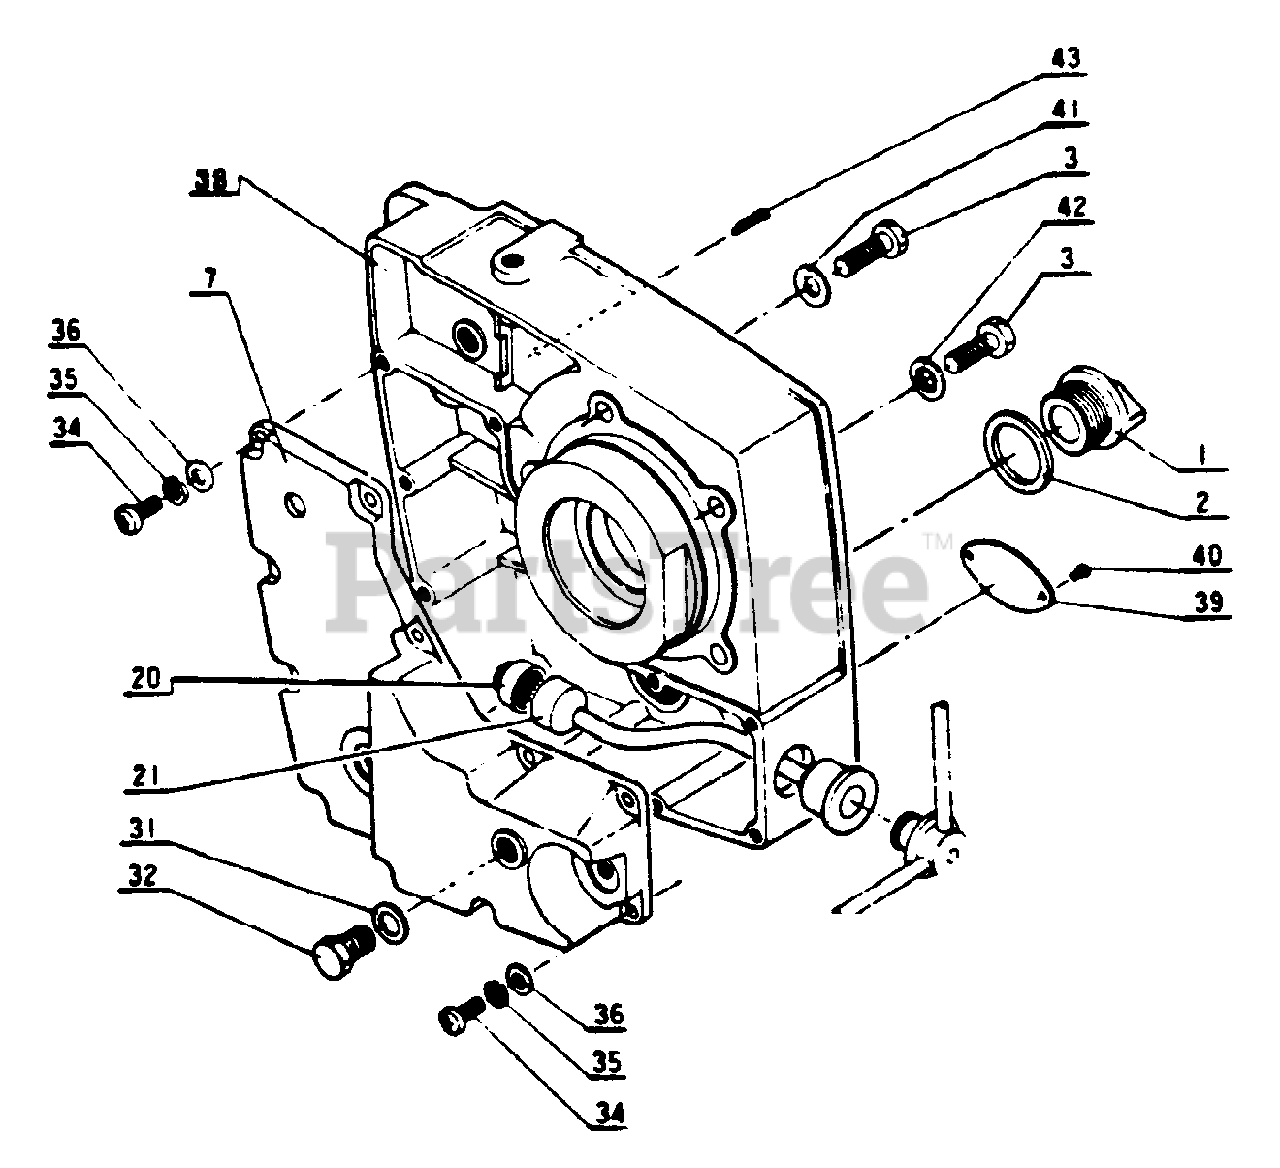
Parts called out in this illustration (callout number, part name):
1	CAP
3	BOLT
7	TANK, OIL
20	FILTER, OIL
21	PIPE, OIL - INNER
31	GASKET
32	BOLT - 8×12
34	SCREW - 4×12
35	WASHER, SPRING 4 MM
36	WASHER 4 MM
38	CRANKCASE
39	MODEL PLATE
40	RIVET
41	WASHER
42	WASHER, SEAL
43	PIN, COTTER
